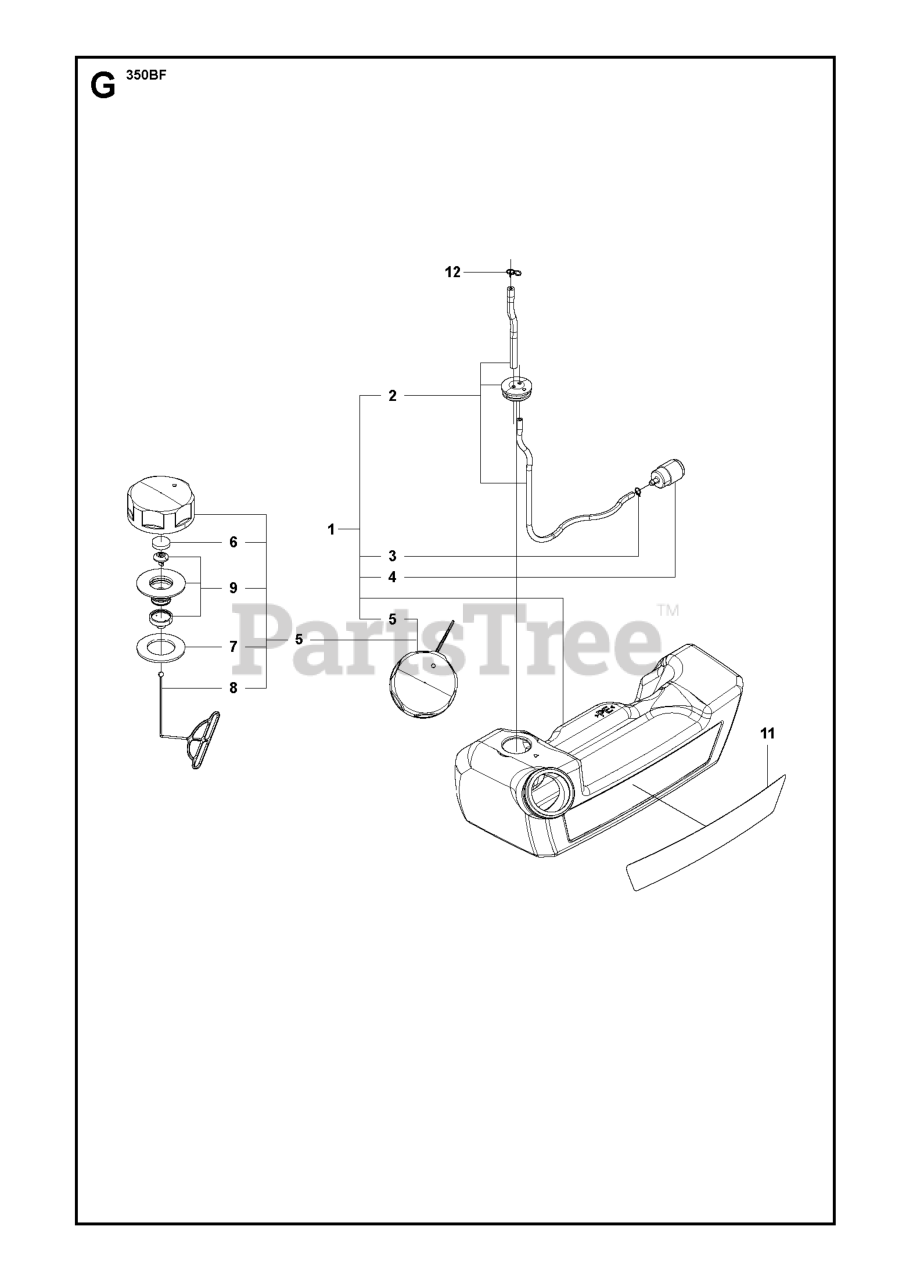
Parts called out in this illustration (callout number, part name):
1	FUEL TANK ASSY
2	Fuel Hoses
4	RP FUEL FILTER
5	ASSY FUEL CAP
